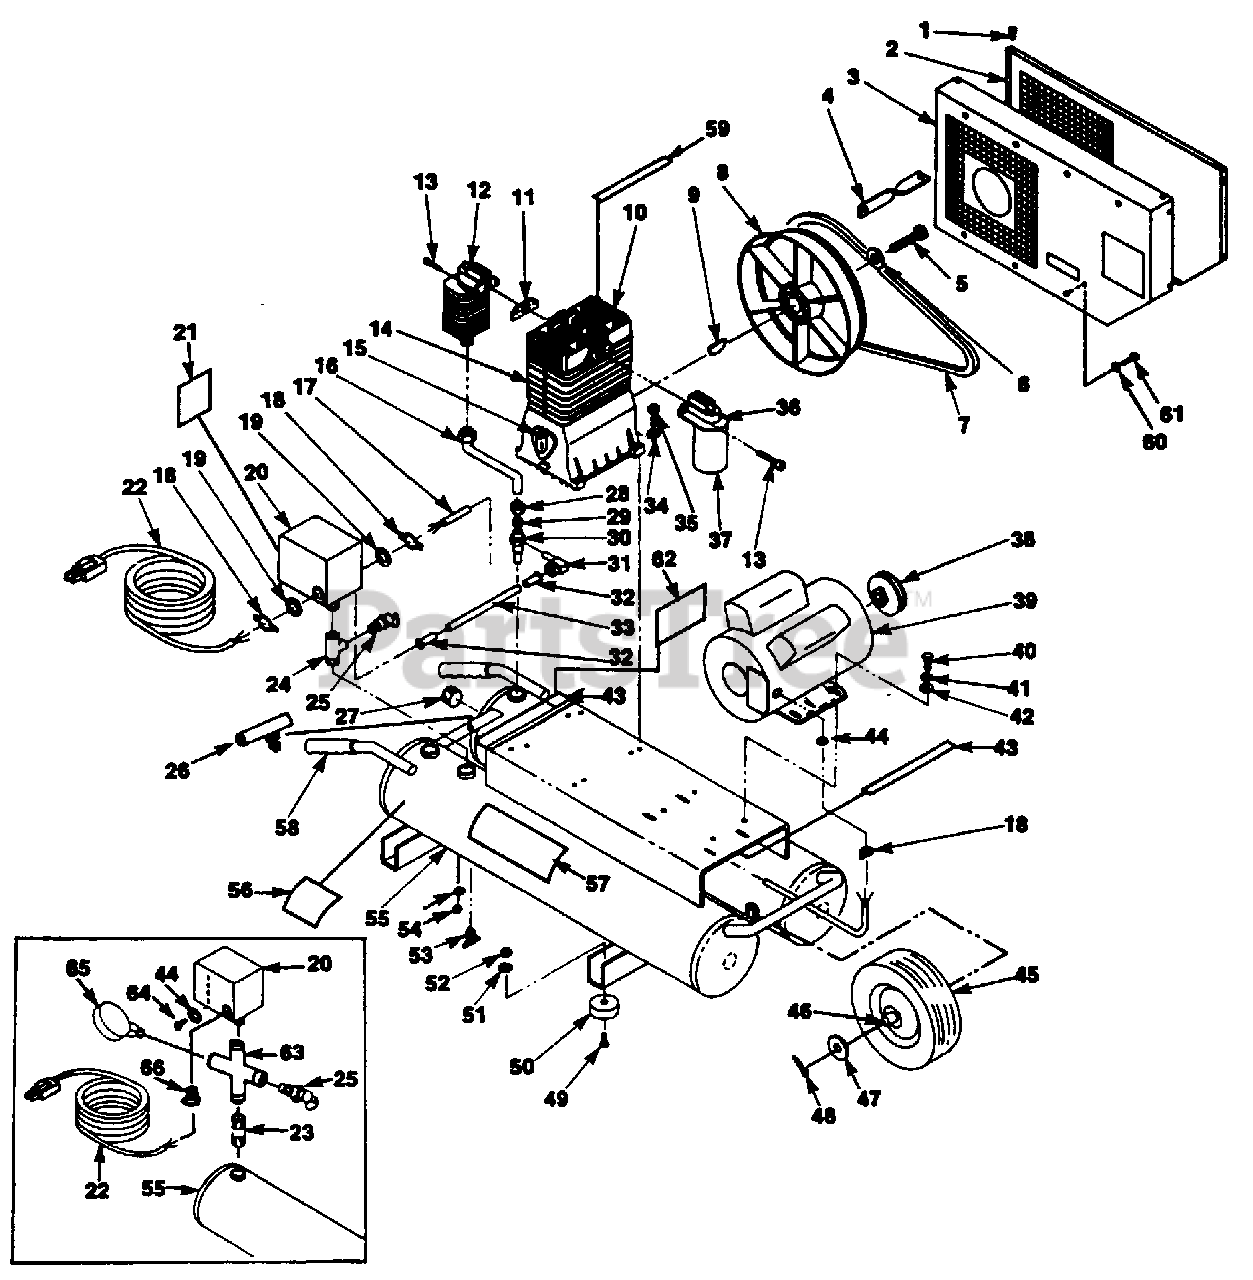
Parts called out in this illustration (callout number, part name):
34	"WASHER, FLAT" TBO
35	SCREW- Hex hd., cap (3/8-16 x 1 1/2")
41	WASHER
42	FLAT WASHER(HSD'S) TBO
51	WASHER, LOCK
52	NUT-(1/4-20)
